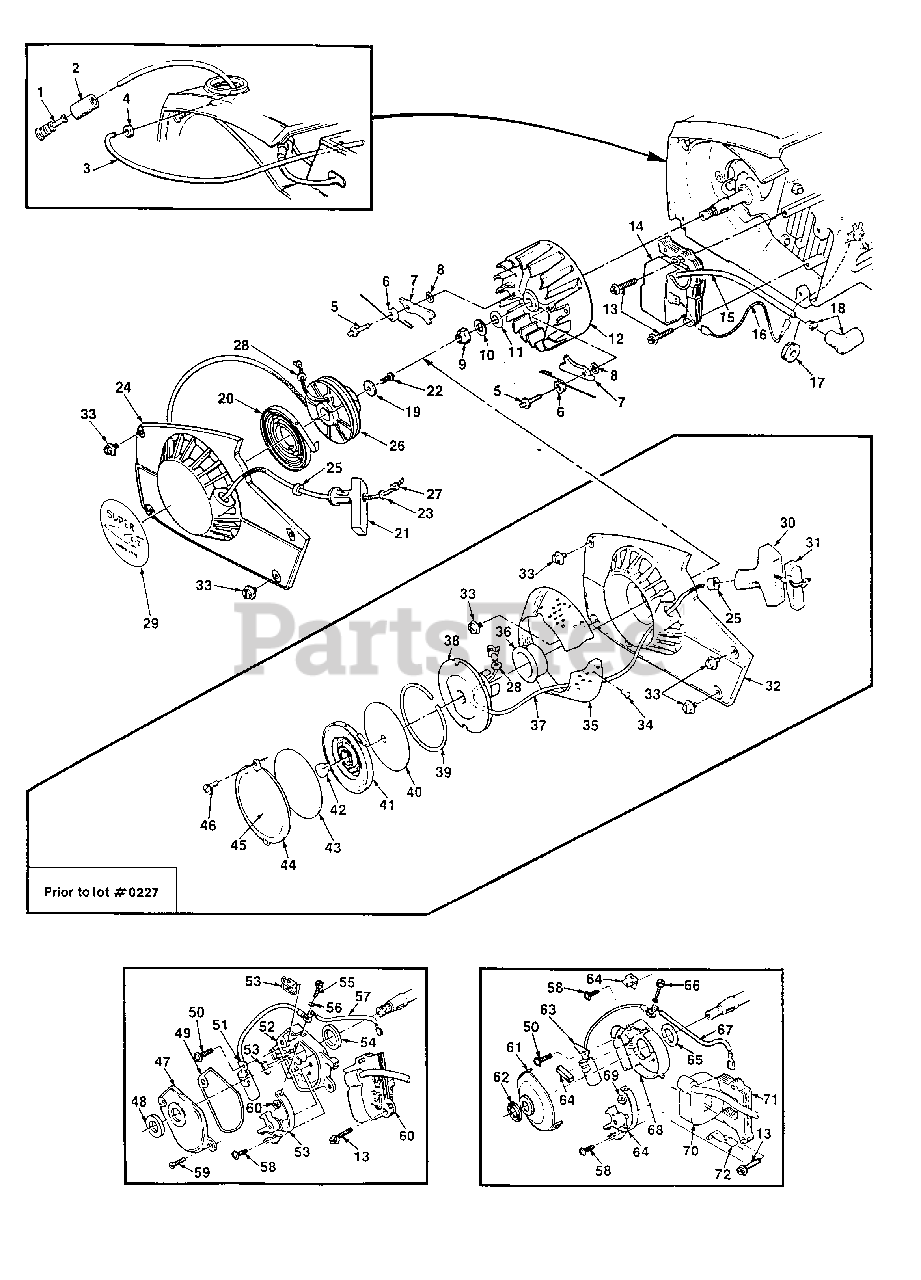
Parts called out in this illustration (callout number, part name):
1	FILTER- Fuel
2	FILTER- Felt
3	LINE- Fuel
4	GROMMET
5	STUD- Starter pawl
6	SPRING- Starter pawl
7	PAWL- Starter
8	WASHER- Lock #10
9	NUT- Hex (5/16 - 24)
10	WASHER- Lock
11	WASHER- Flat 5/16
12	ROTOR- Magneto
13	SCREW- Hex washer hd 8-32 x 3/4
14	MODULE & CORE
15	LEAD- High tension
16	LEAD- Ground
17	GROMMET- Hi tension lead
18	TERMINAL- Spark plug
19	WASHER- Retaining
20	SPRING- Rewind
21	GRIP- Starter rope
22	SCREW- Thrd forming
23	WASHER- Flat
24	HOUSING- Starter & bushing
25	BUSHING- Rope
26	PULLEY- Starter
27	ROPE- Starter #4 34"
30	GRIP- Starter rope
31	INSERT- Rope retaining
32	HOUSING- Rewind starter
33	SCREW- Hex. 10-32 x 5/8
34	STUD- Drive #2
35	SCREEN- Air inlet
36	BUSHING- Starter cup
37	ROPE- Starter 42" (#4)
38	PULLEY & CUP- Starter
39	RING- Shield retaining
40	SHIELD- Spring (Outer)
41	SPRING- Rewind
42	LOCK- Spring
43	SHIELD- Spring (Inner)
44	COVER- Rewind starter
45	DECAL- Starter cover
46	SCREW- Pan 8-32 x 3/8
47	COVER- Breaker box
48	SEAL- Breaker box cover
49	GASKET- Breaker box cover
50	SCREW- Pan 6-32 x 1/2
51	CONDENSER
52	BOX- Breaker
53	POINTS- Breaker
54	SEAL- Felt
55	SCREW- Hex 6-32 x 1/2
56	WASHER- Lock #6
57	LEAD GROUP- Primary
58	SCREW- Pan 6-32 x 3/8
59	SCREW- Cover mounting
60	COIL & CORE-
61	COVER- Breaker box
62	SEAL- Breaker box cover
63	CONDENSER-
64	POINTS- Breaker
65	SEAL- Breaker box
66	SCREW- Hex. 6-32 x 7/16
67	LEAD GROUP- Primary
68	BOX- Breaker
69	NUT
70	COIL- Ignition
71	CORE- Coil
72	RETAINER- Coil
